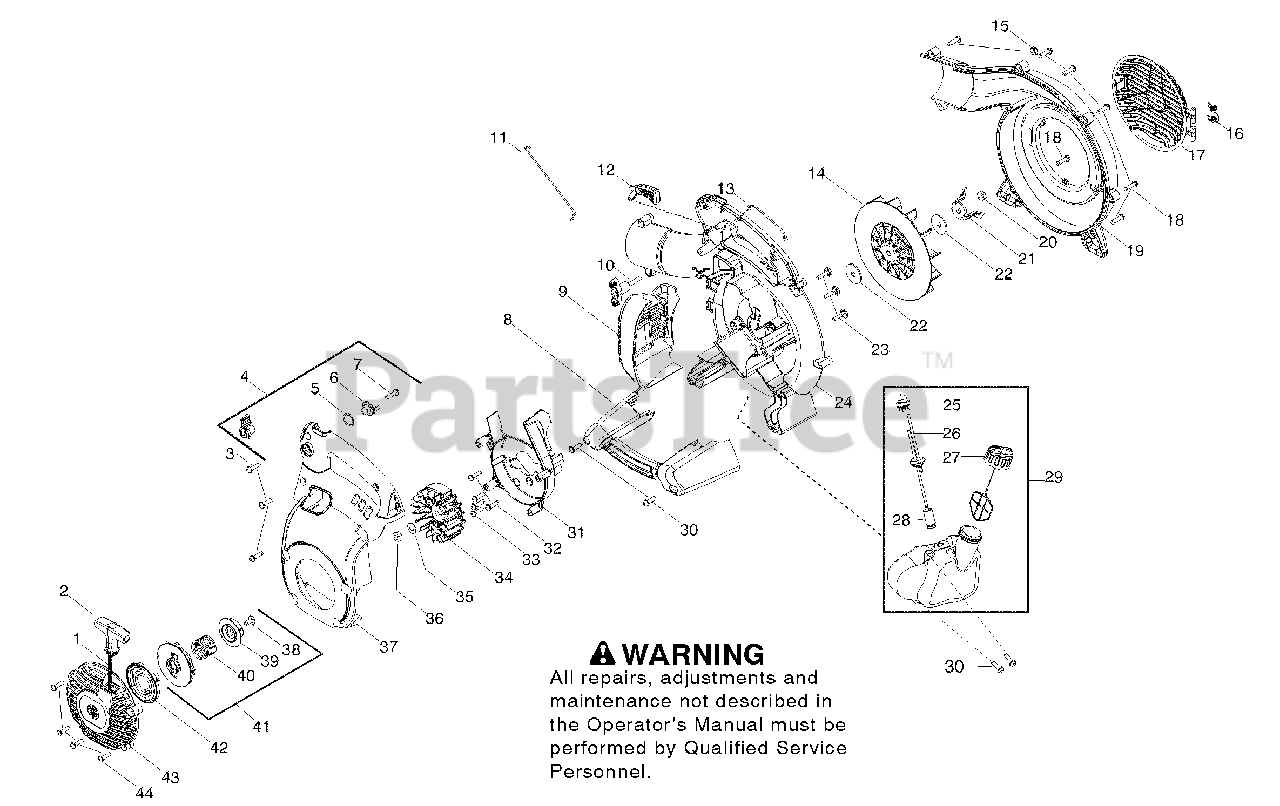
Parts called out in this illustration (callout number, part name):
1	Kit - Rope
2	Handle - Starter
4	Kit - Cruise control
5	Washer - Wave
6	Ratchet - Cruise control
8	Handle - Assist
9	Assy. - Muffler guard
10	Assy. - Knob tube clamp
11	Wire - Linkage
12	Trigger - Throttle
13	Wire - Handle ground
14	Impeller
15	Nut - Blower tube
16	Spring - Vac door
17	Cover - Vac door
19	Assy - Outer scroll
20	Nut - Impeller
21	Blade - Mulch
22	Washer - Impeller
24	Scroll - Inner
25	Bulb - Purge
26	Kit - Fuel line grommet
27	Assy - Fuel cap with retainer
28	Assy - Fuel pickup
29	Assy - Fuel tank
31	Scroll - Flywheel
33	Screw
34	Assy - Flywheel
36	Nut - Flywheel
37	Cover - Motor housing
40	Spring - EPS2
41	Kit - Starter
42	Spring - Starter
43	Housing - Starter Cover
44	Screw
